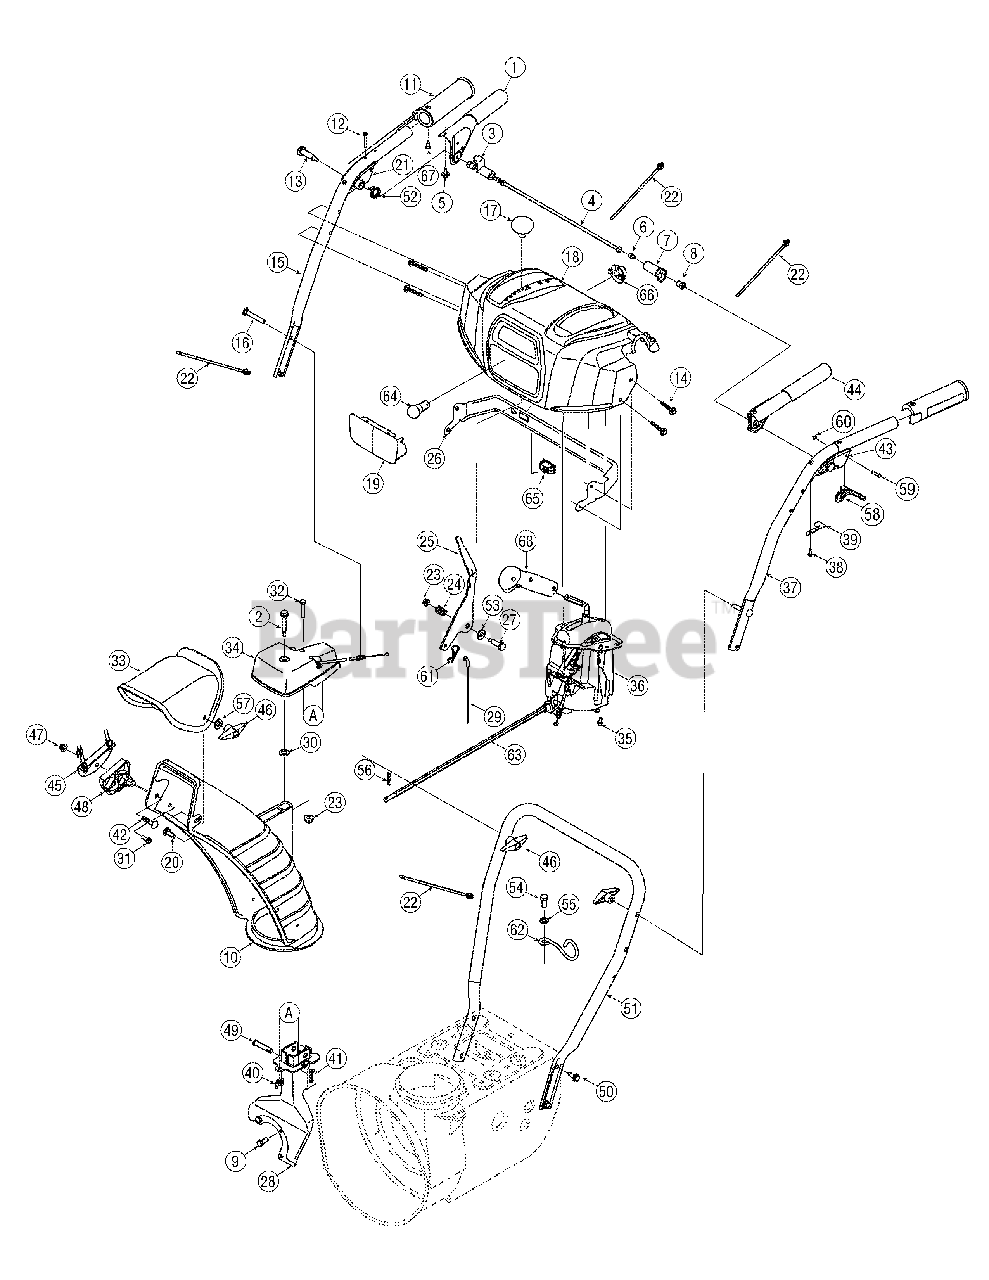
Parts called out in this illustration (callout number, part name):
1	Handle Engagement Assembly RH
2	Flange Shoulder Screw
3	Lock Plate
4	Pivot Rod
5	Rubber Bumper
6	Screw, 1/4-20 x .500
7	Clutch Lock Cam
8	Shoulder Nut, 1/4-20
9	Hex Screw, 5/16-24 x .750
10	Lower Chute
11	Heated Grip
12	Screw, #10-24 x 0.375
13	Shoulder Screw, 1/4-20
14	Screw, 1/4-20 x 1.625
15	Upper Handle RH
16	Carriage Screw, 5/16-18 x 2.25
17	Shift Knob
18	Handle Panel
20	Carriage Bolt, 5/16-18 x 1.0
21	Handle Clutch Lock RH Assy
22	Cable Tie
23	Flange Lock Nut, 1/4-20
24	Compression Spring
25	Shift Lever
26	Panel Bracket
27	Shoulder Screw
28	Chute Support Bracket
29	Speed Selector Cable
30	Flat Washer, .25 x .630 x .0515
31	Hi-Lo Screw, 1/4-15 x .75
32	Hex Screw, 1/4-20 x 3.00
33	Upper Chute
34	4-Way Chute Gearbox Assembly
35	Hi-Lo Screw, 1/4-15 x 0.5
36	4-Way Chute Control™ Assembly
37	Upper Handle LH
38	Screw, #8-16 x 0.50
39	Clutch Lock Spring
40	Wing Nut, 1/4-20
41	Bow Tie Cotter Pin
42	Carriage Bolt, 5/16-18 x 1.50
43	Handle Clutch Lock LH Assy
44	Handle Engagement Assembly LH
45	Cable Bracket
46	Wing Knob
47	Flange Lock Nut, 5/16-18
48	Chute Tilt Cable Guide
49	Clevis Pin
50	Screw, 5/16-18 x 0.75
51	Lower Handle
52	Torsion Spring
53	Flat Washer
54	Screw, M8-1.25
55	Flat Washer, .330 x .630 x .0635
56	Cotter Pin
57	Flat Washer, .349 x .879 x .063
58	Steering Control
59	Pin, 3/16
60	E-Ring
61	Click Pin
62	Cable Guide
63	Chute Rod
65	Switch, Heated Grip
66	Light Socket
67	Scr., AB, #10-16 x .625
68	Handle Assembly
